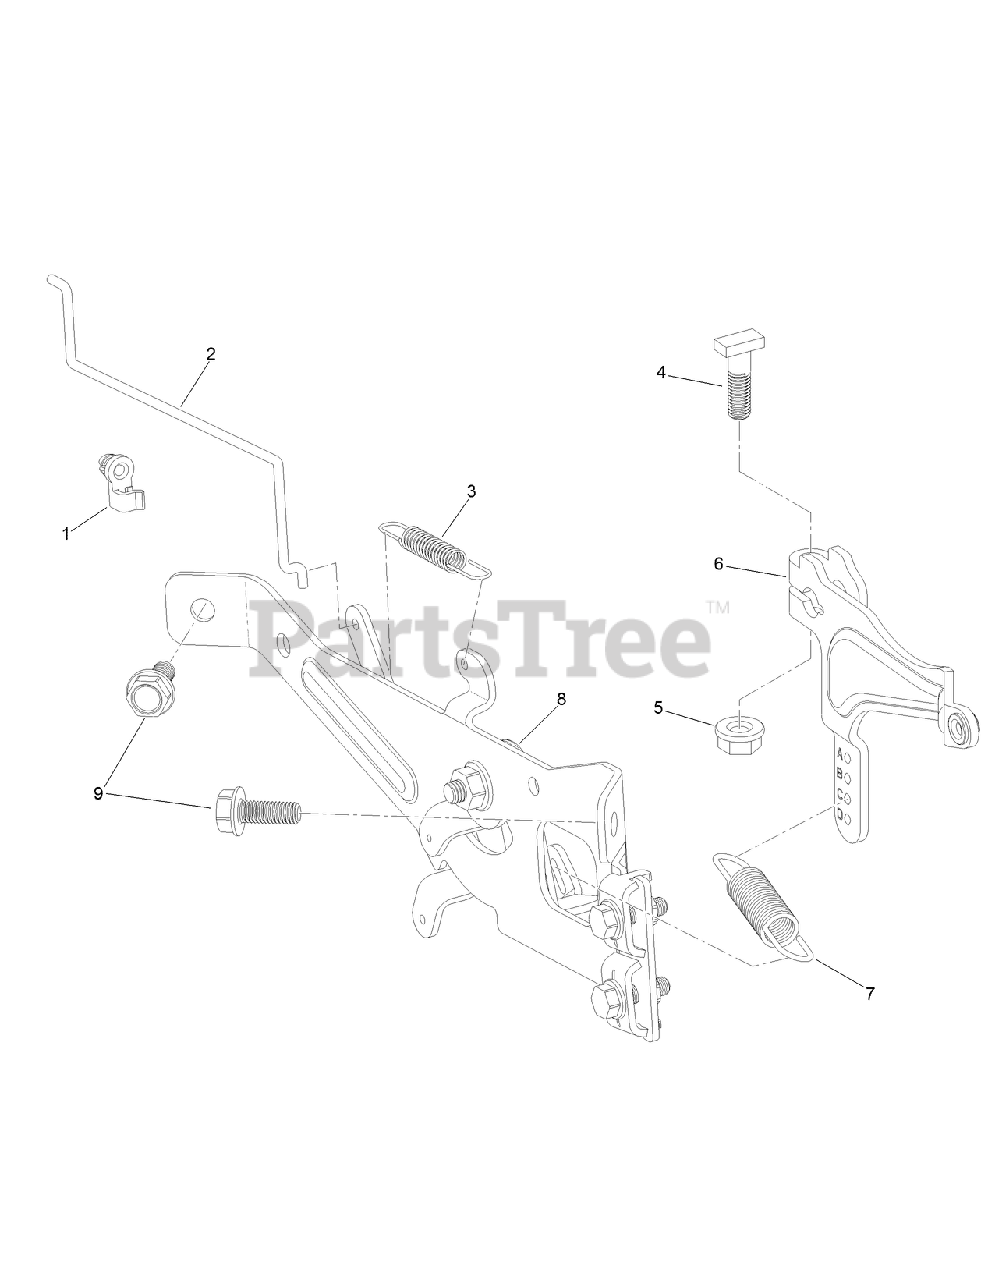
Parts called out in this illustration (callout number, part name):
1	CLIP-LINKAGE
2	LINKAGE-CHOKE
3	SPRING-GOVERNOR
4	BOLT-ARM, GOVERNOR
5	NUT-FLANGE
6	ARM-GOVERNOR
7	SPRING-GOVERNOR
8	PLATE-CONTROL
9	SCREW-HHF
